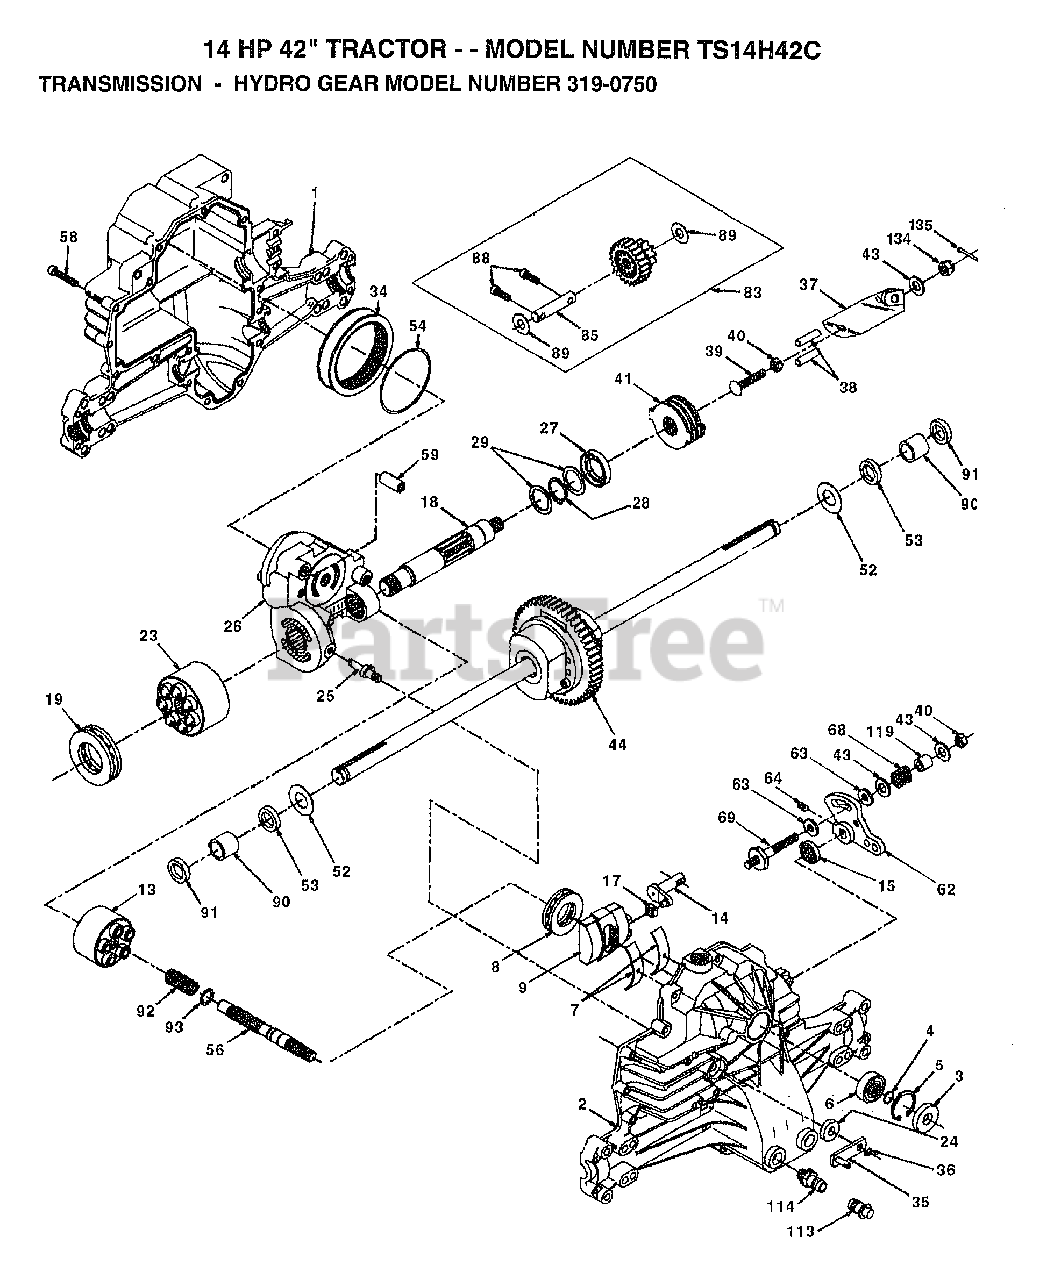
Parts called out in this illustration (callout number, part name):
1	HOUSING.L.50074RM
2	HOUSING.UP.70125
3	SEAL.9008000-0128
4	RING.RET.2003016.
5	RING.RET.2003052.
6	BEARING.(50552)42X68X16
7	CRADLE- 2003023.
8	BEARING.2003044.
9	SWASHPLT.2003087.
13	BLOCK.CLYN.70079.
14	ARM.TRUN.2003005.
15	SEAL.9008000-0126
17	GUIDE.2000015.
18	SHAFT.MOTOR.50115
19	BEARING.THS.50019
23	BLOCK.CYLIN.70082
24	SEAL.LIP.45074
25	ACTUATOR.2003555
26	KIT.CENTER.70133
27	SEAL.LIP.45075
28	RING RETAIN 50007
29	WASHER.44872
34	ELEMENT.OIL.44964
35	ARM.BYPASS.50270
36	RING.RETAIN.44870
37	ARM.ACTUAT.23710
38	PIN.ACTUAT.44891
40	NUT.LOCK.HX.50108
41	KIT.BRAKE.70135
43	WASHER HYD 44130
44	DIFFERENTIA.70130
52	WASHER.HYD.50152
53	SEAL.HYDRO.45076
54	O RING.HYD.45077
56	SHAFT.INPUT.50005
58	BOLT.1/4-20.44876
59	PIN.HYDRO.50002
62	ARM.CONTROL.50254
63	PUCK.DAMPER.50281
64	SCREW.SET.50018.
65	BOLT #8-32 X .875
68	SPRING.HYD.50277
83	JACKSHAFT/PINION GEAR.70132
85	JACKSHAFT.50086
88	SCREW.CAP.50154.
89	WASHER.HYD.50132
90	BEARING.SLV.50118
91	SEAL.WIPER.50941
92	SPRING.2003014.
93	WASHER.2003017
113	CAP.VENT.70109
114	O-RING.ASM.70110
119	SPACER.HYD.50278
